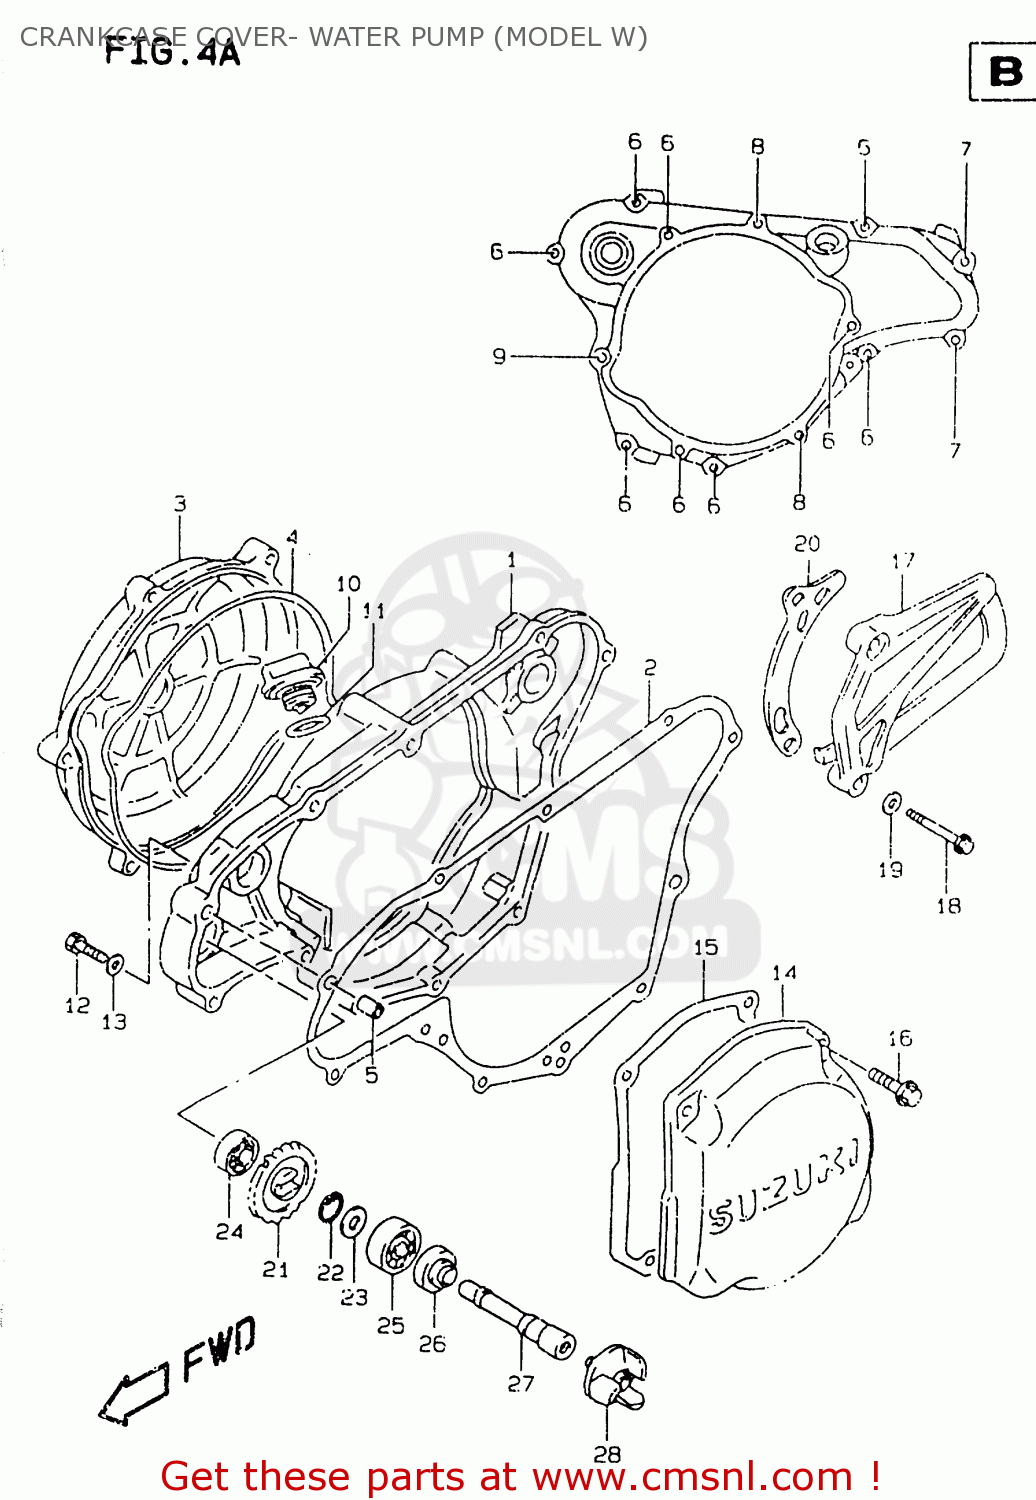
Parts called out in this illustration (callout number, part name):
1	COVER,CLUTCH
2	GASKET,CLUTCH COVER
3	COVER,CLUTCH,OUTER
4	O RING,CLUTCH COVER OUTER
5	PIN
6	SCREW
7	BOLT,G/S SWITC
8	BOLT
9	BOLT
10	PLUG,OIL FILLER
11	O RING(D:3.1,ID:16.8)
12	SCREW(6X10)
13	GASKET(6.2X11X1).2 (NAS)
14	COVER,MAGNETO
15	GASKET,MAGNETO COVER
16	SCREW
17	COVER,ENGINE SPROCKET
18	BOLT,G/S SWITC
19	WASHER(6.5X14X2)
20	PLATE,FR CHAIN GUIDE
21	GEAR,WATER PUMP DRIVEN
22	CIRCLIP,10MM
23	SHIM(10X14X1)
24	BEARING(8X22X7)
25	BEARING(10X26X8)
26	SEAL,WATER PUMP OIL
27	SHAFT,WATER PUMP
28	IMPELLER,WATER PUMP
